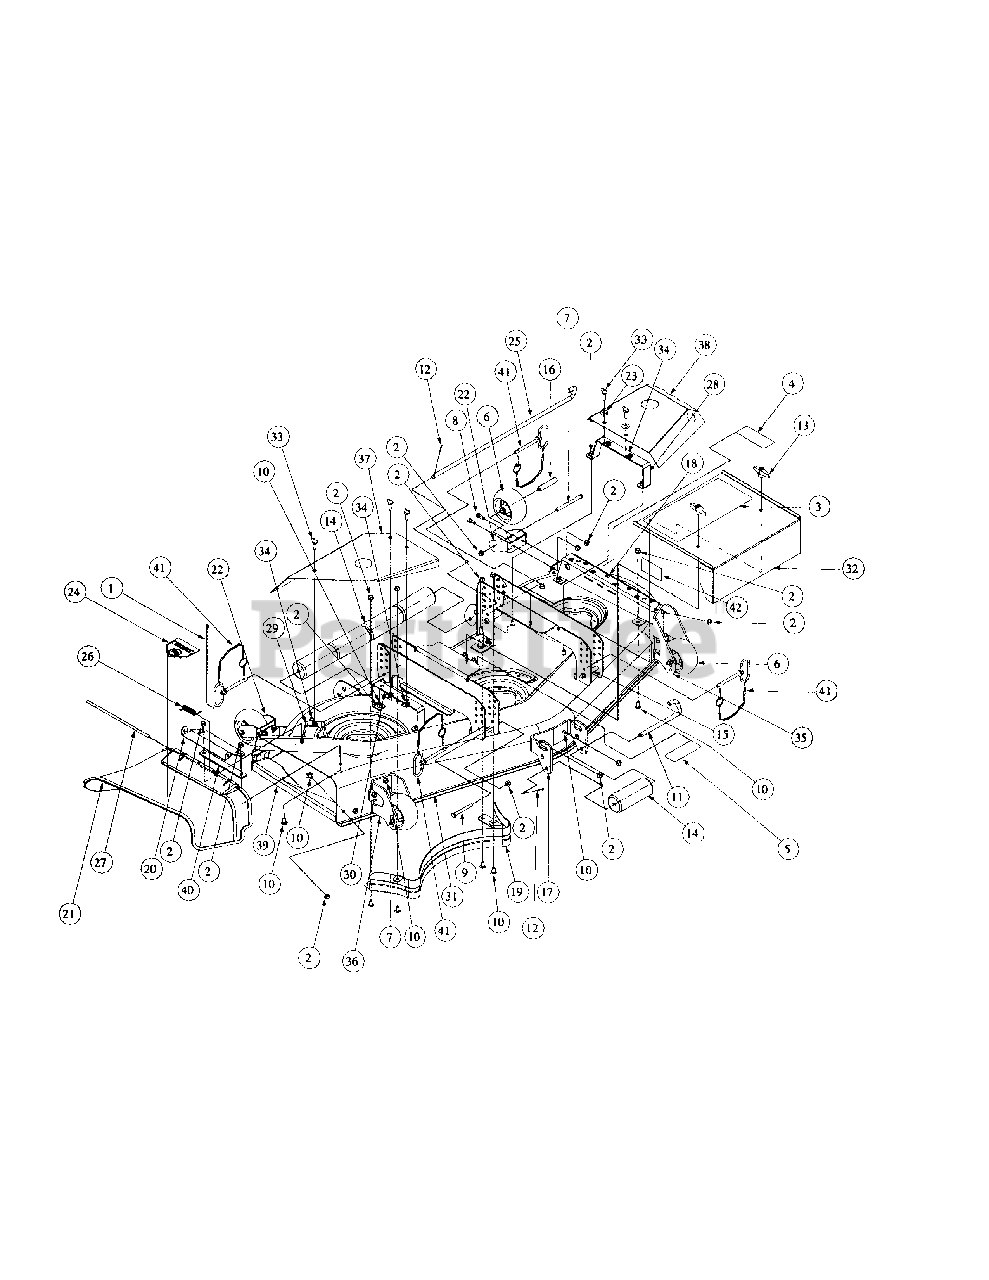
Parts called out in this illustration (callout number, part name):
1	Cable Tie, 3/16 x 05 x 7.4
2	Hex, Nut, Flange Lock, 3/8-16
3	Label, MTD Pro 60
4	Decal, Rotating Blade
5	Decal, Warning Shield Missing
6	Complete Wheel, 5 00 Dia
7	Hex, Cap, Screw, 3/8-16, 4.25
8	Hex, Cap, Screw, 3/8-16, 88
9	Hex, Cap, Screw, 3/8-16, 3.25
10	Carriage Bolt, 3/8-16 x 75 Long
11	Roller Pin, 1/2" Dia. x 7.31 Long
12	Cotter Pin, 1/8 x 1.0
13	Knob Assembly, Wingnut, 5/16-18
14	Front Roller
15	Deck, Stop, Spacer
16	Wheel, Spacer
17	Front 54, Roller Bracket
18	60" Deck, Brace Assembly
19	Rear, Deck, Baffle
20	Chute, Deflector, Bracket
21	60" Deck, Chute Deflector
22	Caster Bracket
23	Belle Washer, .325 x .930 x 045
24	Decal, Danger Hands and Feet
25	Roller, Pin
26	Torsion, Spacer, 0.4 ID x 2.16 Long
27	Chute, Deflector, Rod
28	60 Left Hand, Belt Cover, Support Bracket
29	60 Right Hand, Belt Cover, Support Bracket
30	60 Center Belt Cover, Support Bracket
31	Mower, Deck Assembly
32	60 Center, Belt, Cover
33	Thumb Screw, 5/16-18 x 1.0 Long
34	U-Nut, 5/16-18
35	Front Left Hand, Deck, Bracket
36	Front Right, Support Bracket
37	60 Deck, Right Hand, Belt Cover
38	60 Deck, Left Hand, Belt Cover
39	Toe Guard Assembly
40	Strip Spacer, 0.1875 Thick
41	Deck Pin, 3/8" Dia
42	Label, Height of Cut
